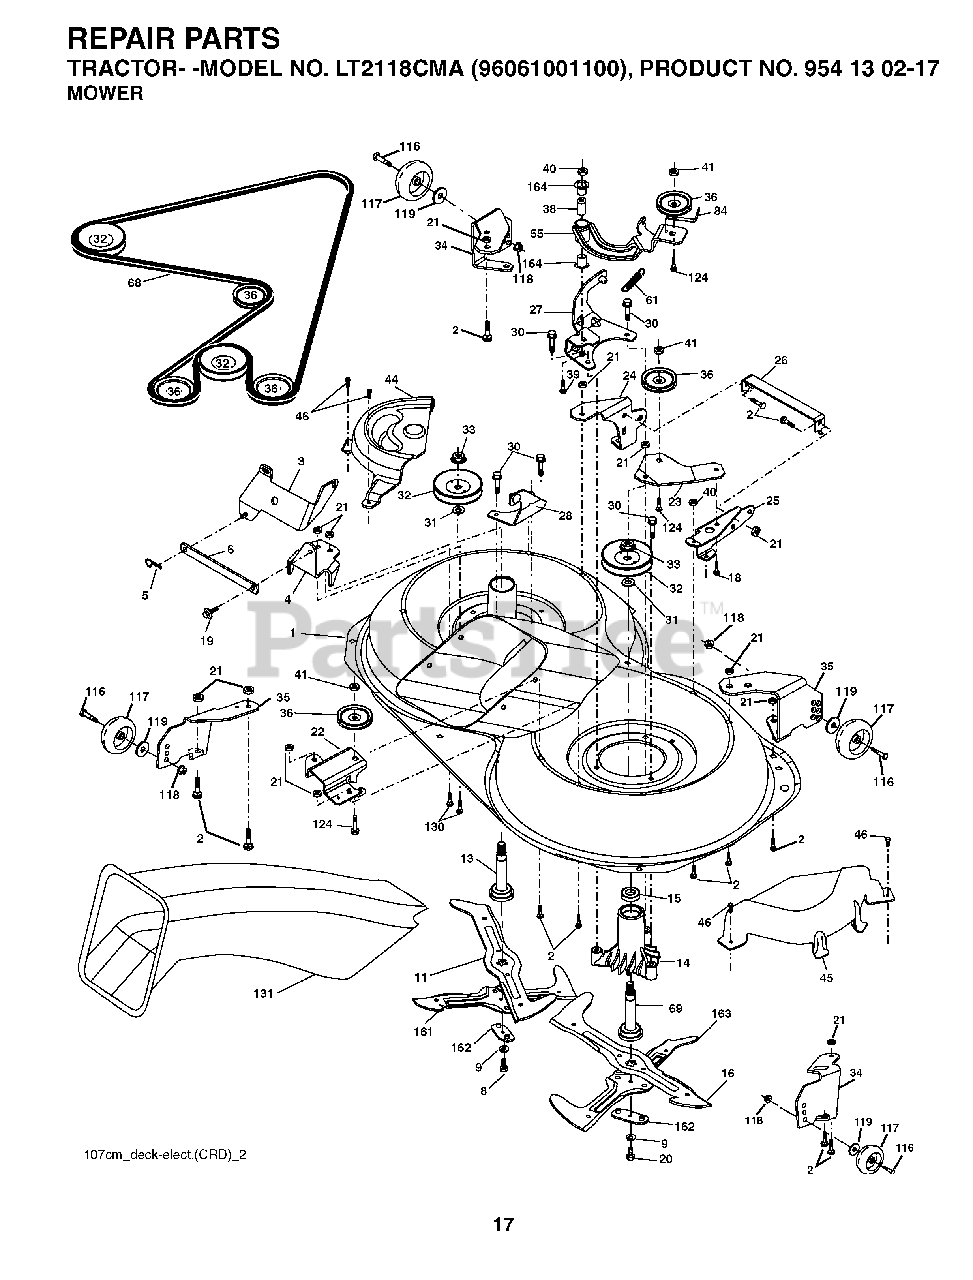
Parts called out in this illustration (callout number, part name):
2	BOLT
3	BRACKET
5	RETAINER-SPRNG RB
6	BAR SWAY
9	LOCKWASHER
11	BLADE.3N1.LH.CRD
13	SHAFT ASM VENT
14	HSG MANDREL
16	BLADE.3N1.RH.CRD
19	BOLT SHD 5/16-18
21	LOCKNUT
22	BRACKET
23	BRACKET
26	BRACE
27	BRACKET
30	SCREW, WASHER HEAD
31	WASHER.SPACER.MANDREL
33	NUT, FLG TOPLOCK 9/16"
36	PULLEY.IDLER.4.25
40	LOCKNUT
41	NUT LOCK FLG 3/8-16 UNC
45	MANDREL COVER
46	SCREW.1/4-20X5/8
55	ARM IDLER
68	HEX-BELT 107 MOWER
69	SHAFT.ASM.W/LWR.BRG.RH.THREAD
84	KEEPER, BELT IDLER
116	SHOULDER BOLT
117	WHEEL GAGE DONUT
118	LOCKNUT
119	WASHER
124	BOLT.3/8-16X1.50
131	CHUTE BAGGER
164	BRNG T
